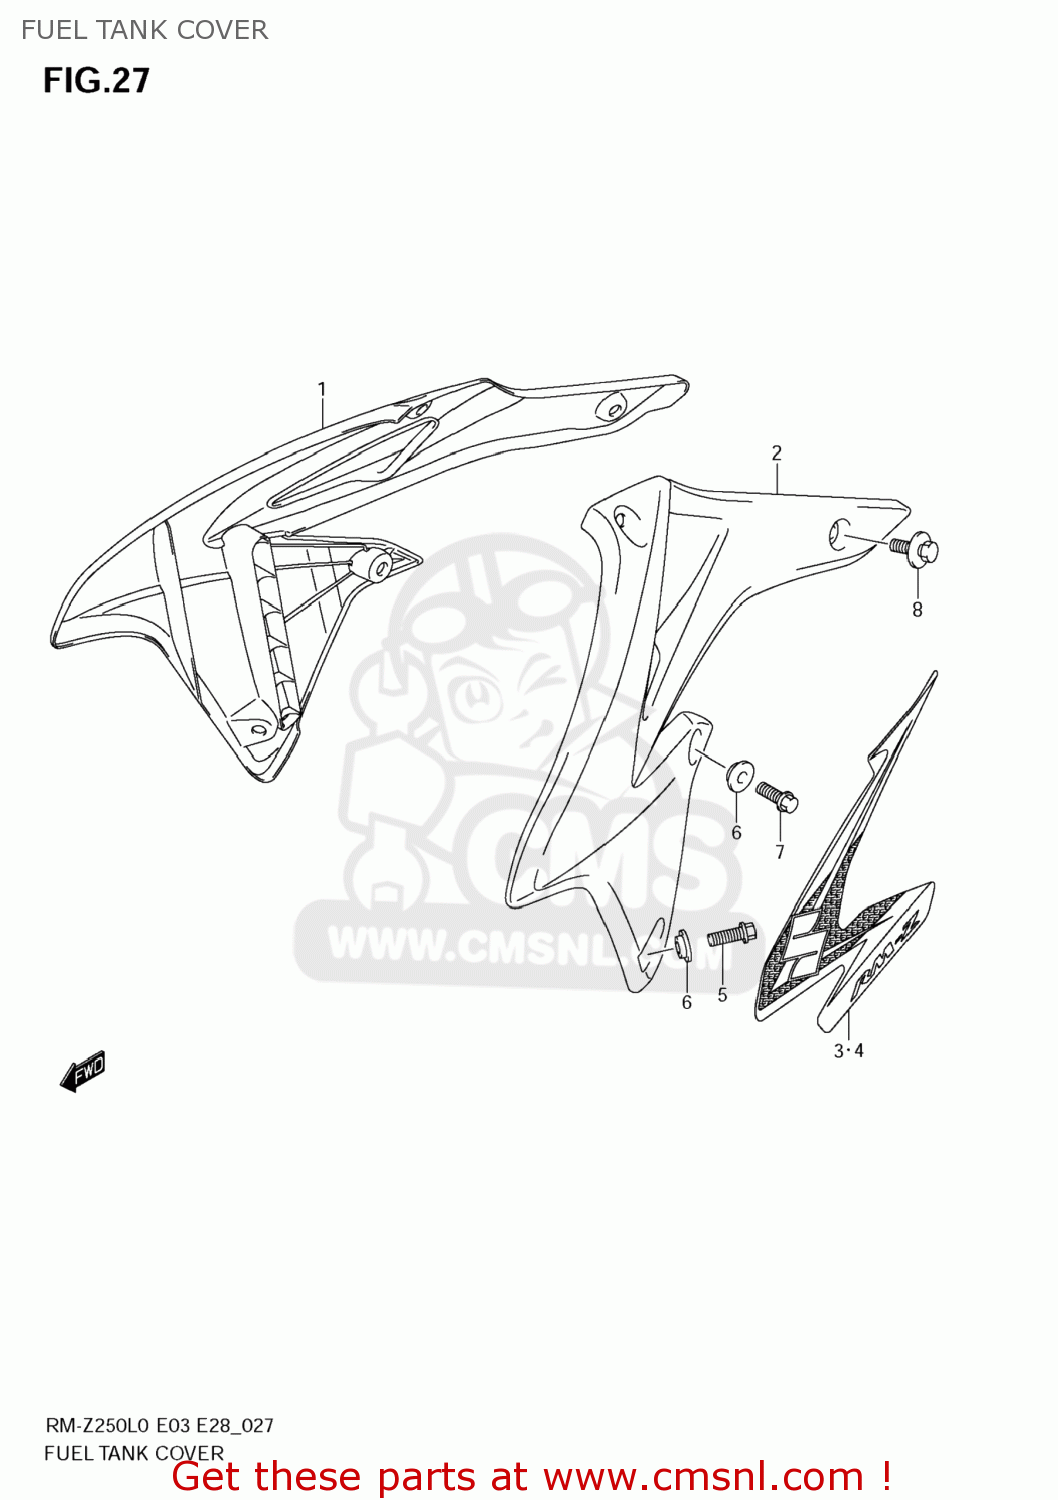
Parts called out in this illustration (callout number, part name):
1	COVER,FUEL TAN
2	COVER,FUEL TANK
3	TAPE,FUEL TANK COVER,R
4	TAPE,FUEL TANK COVER,L
5	BOLT(6X12)
6	WASHER
7	BOLT(6X16)
8	BOLT(6X12)
